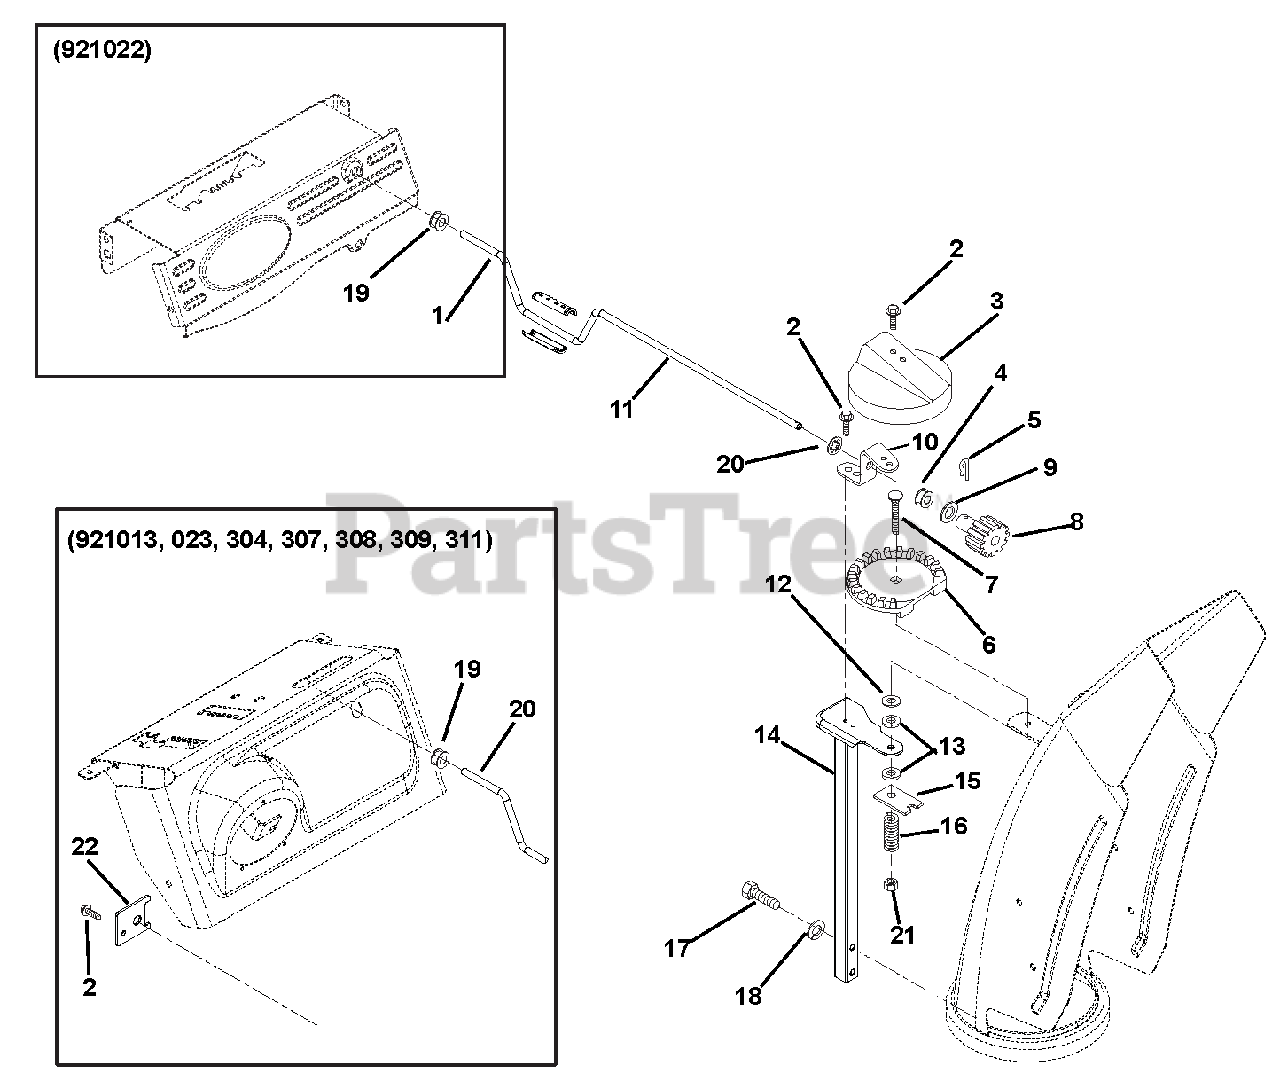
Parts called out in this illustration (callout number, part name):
1	KNOB, CRANK-SNAP
2	SCR-TAP .25-20X.50 HWH TR YWZ
3	GEAR COVER
4	BUSHING, POLYLINER-.63 SNAPIN
5	PIN, SPRING CLIP
6	CHUTE GEAR
7	@BLT-RDHDSQNK .38-16X2.50 G5YZ
8	PINION GEAR W/BRACKET
9	WSHR-THRST .625 X 1.0 X .03
10	BRACKET, PINION GEAR
11	PUSHNUT .625
12	WSHR-FL-STL .380X1.50X.062 YWZ
13	FRICTION WASHER
14	PEDESTAL, CHUTE - CRANK
15	PLATE, FRICTION
16	SG-COMP .187X.56X1.62
17	@BLT-HEX .38-16X1.75 GR5 YWZC
18	@WSHR-LK .38X.094 REG YWZC
19	BUSHING, POLYLINER-.38 SNAPIN
20	ROD, CHUTE CRANK
21	@NUT-LK-TOP-FLG .38-16 YWZC
22	BRACKET, CHUTE CRANK
